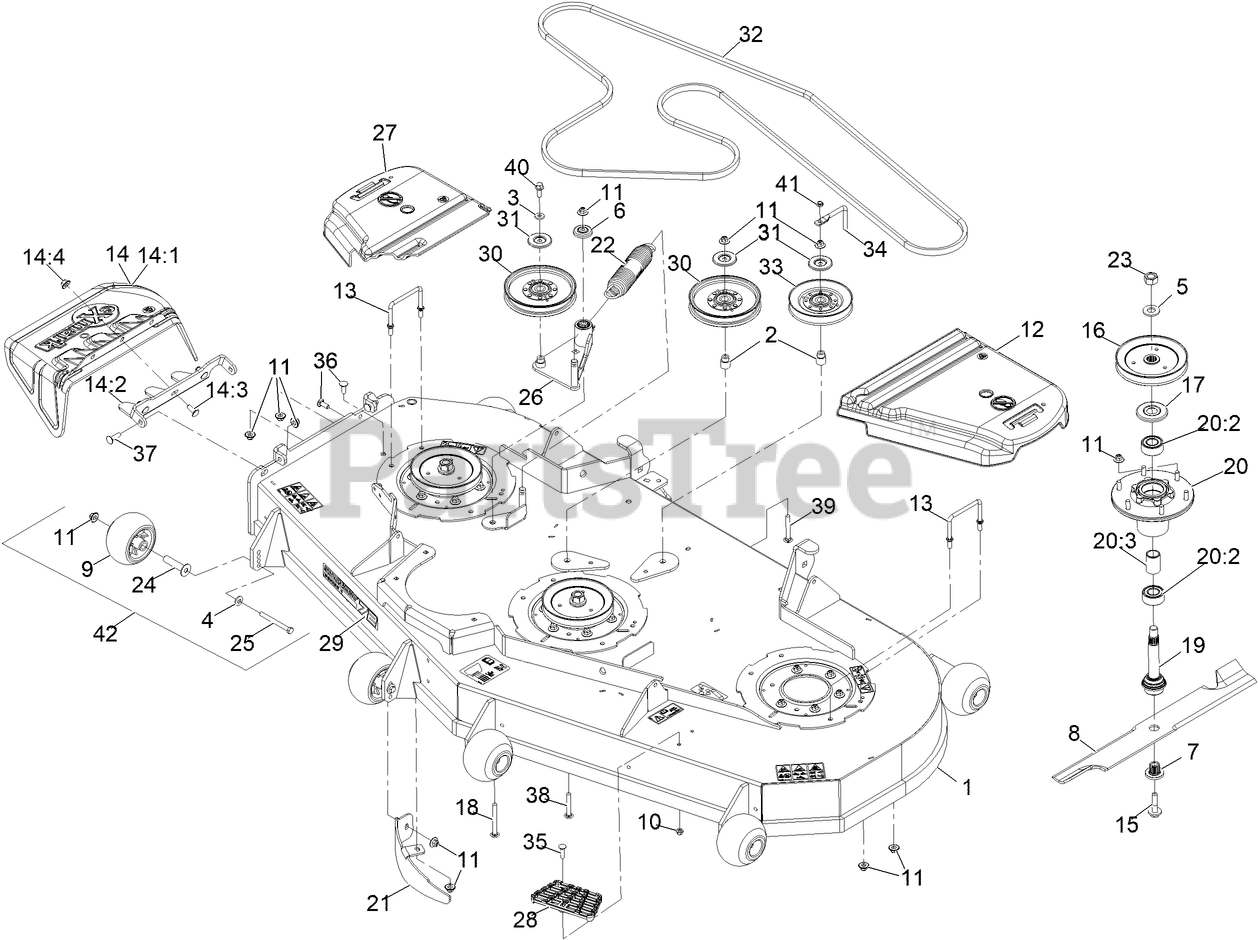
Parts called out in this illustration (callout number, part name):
1	DECK-724
2	BUSHING-IDLER
4	WASHER-BELLEVILLE
6	GUARD-TOP
7	BUSHING,SPLINED
9	ROLLER-SCALP, ANTI
10	NUT-HF, NI
11	Nut-Nyloc 3/8-16 Flg
12	COVER-BELT, LH
13	WIREFORM-COVER
14	ASM,DISCHARGE CHUTE
14:1	CHUTE,DISCHARGE
14:2	BRACKET,DISCHARGE CHUTE
14:3	SCREW-CARR
14:4	Nut-Nyloc 3/8-16 Flg
15	SCREW,SEMS 1/2-20 X 2.19
16	SHEAVE,BLADE DRIVE 6.50
17	GUARD-BEARING, TOP
18	BOLT-SHOULDER, CARRIAGE 3/8-16 X 3 1/2
19	ASM-SPINDLE AND SEAL
20	ASM-CUTTER HSG
20:2	BEARING-3205 TRASHGUARD
20:3	SPACER-BEARING
21	BAFFLE-DOGLEG, LZ72
22	SPRING-EXTENSION
23	NUT-HEX
24	AXLE, ROLLER
25	SCREW-HH 3/8-16 X 3 3/4 GR 8
26	IDLER ARM ASM
27	SHIELD-BELT
28	STEP-DECK
29	DECAL, 724
30	IDLER-PULLEY
31	SHIELD-DUST
33	IDLER V
34	GUIDE-BELT
35	Bolt-Carriage 5/16-18 X 1 1/4
36	SCREW-CARR
37	Bolt-Carriage 3/8-16 X 1 1/4
38	SCREW-CARR
39	SCREW-CARR
40	SCREW-HHF
42	KIT, ANTI-SCALP ROLLER
